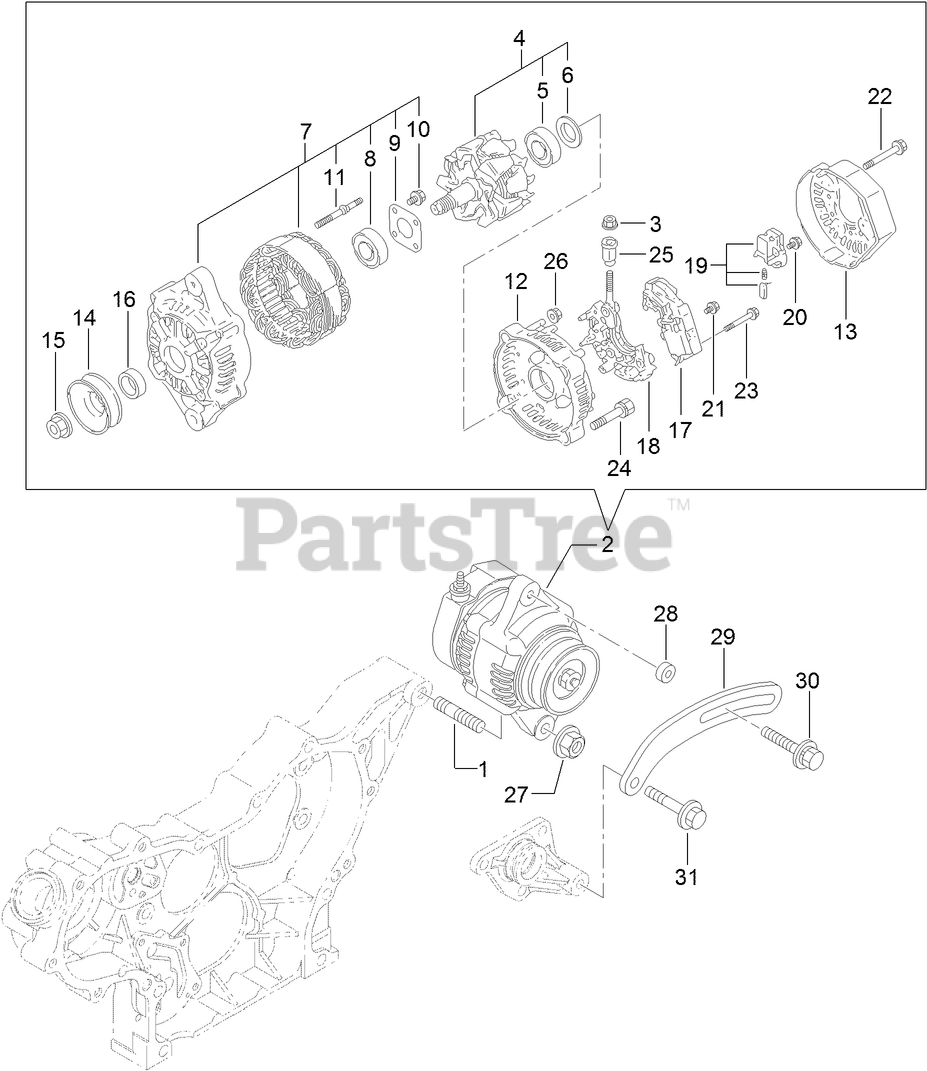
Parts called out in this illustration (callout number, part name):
2	GENERATOR
4	ROTOR ASM
5	BEARING-BALL
7	FRAME ASM
8	BEARING-BALL
9	PLATE-RETAINER
14	PULLEY
16	COLLAR
17	REGULATOR ASM
18	HOLDER
19	HOLDER
25	BUSHING-INSULATION
28	SPACER
29	ADJUSTER
